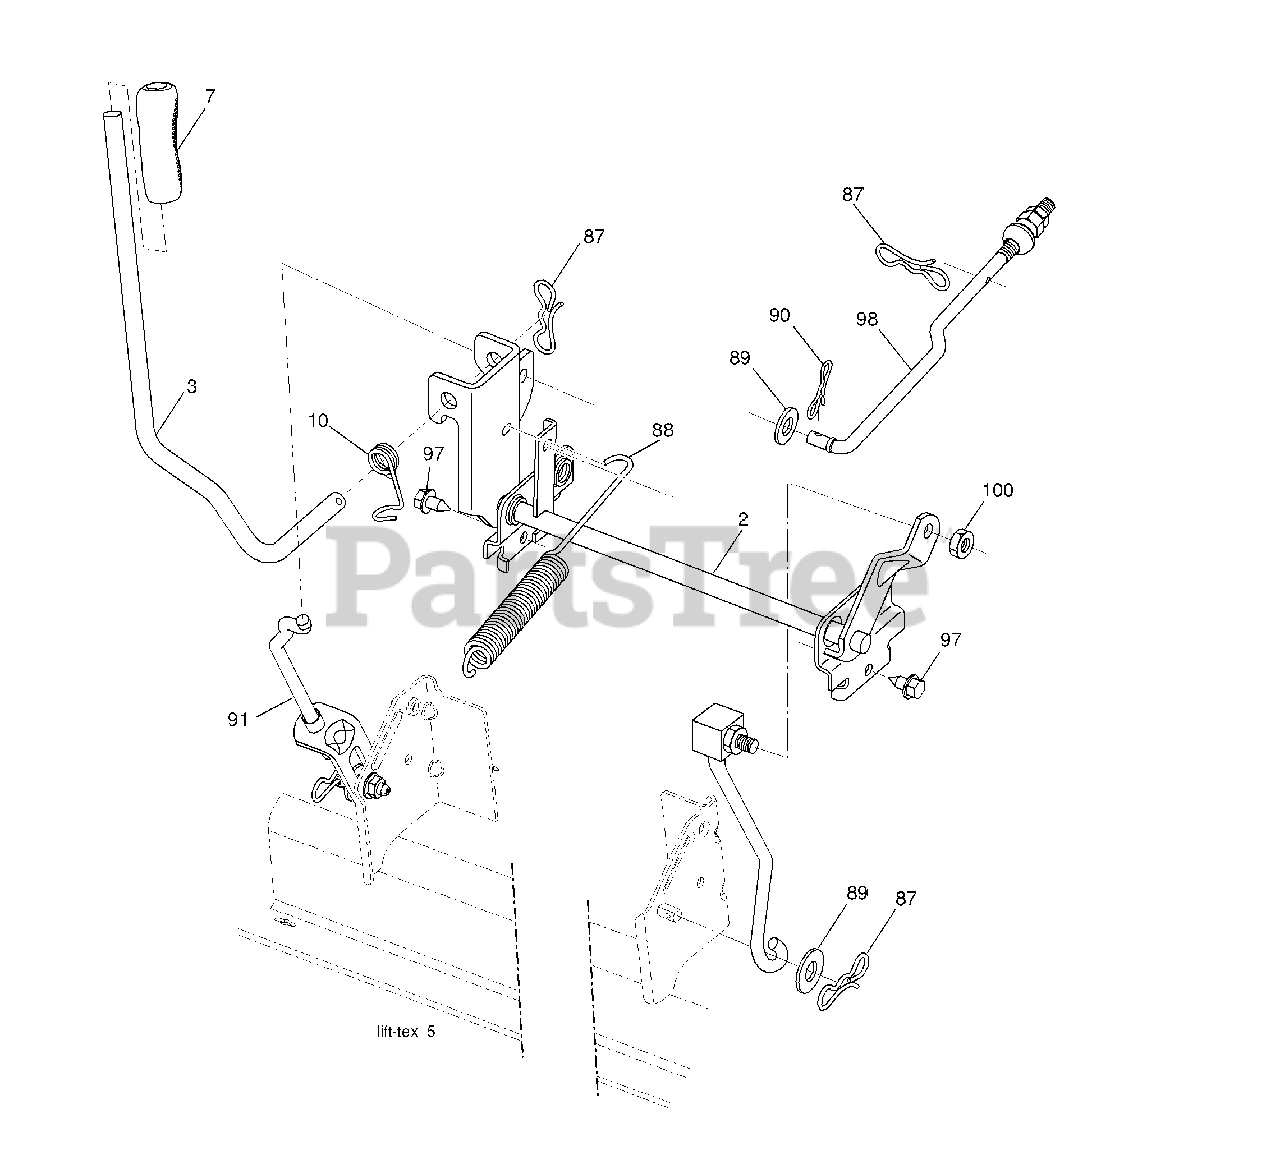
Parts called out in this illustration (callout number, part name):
2	Shaft Asm., Lift
3	Lever Asm., Lift RH
7	Grip, Lever
10	Spring Torsion
87	Pin Cotter 7/16 Bow Tie Lock
88	Spring Lift Assist
89	Washer Clear Zinc
90	Pin Cotter 5/16 Bow Tie Lock
91	Link Asm Lift LH Rear
97	Screw 3/8-16 x .75 Smgml Tap/R.Z
98	Link Lift Susp. Front Mower
100	Nut Hex Jam ASF 7/16-20 unf
